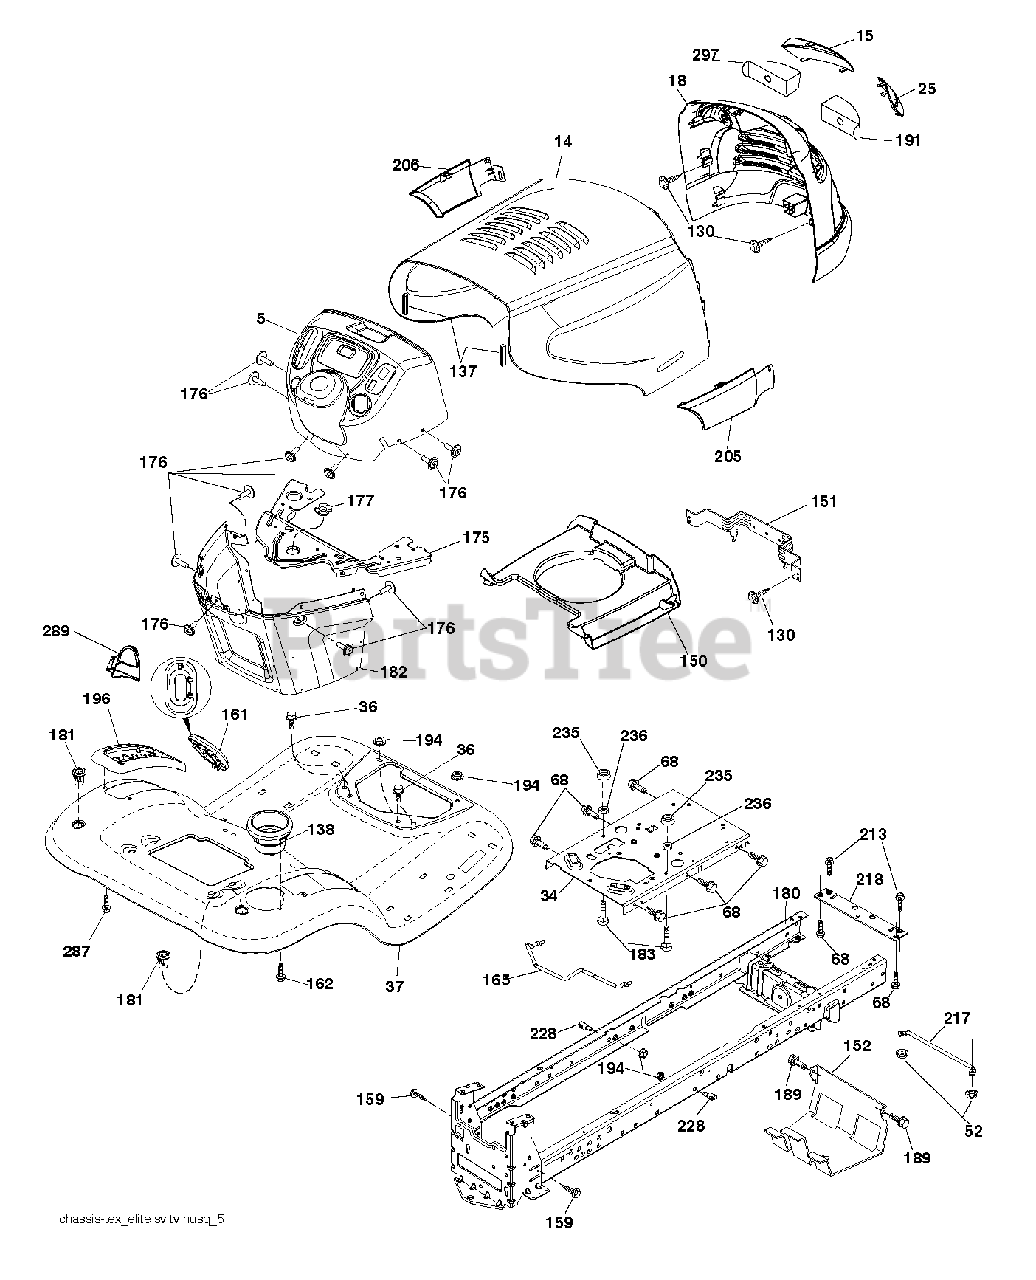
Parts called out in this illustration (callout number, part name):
5	DASH UPPER
14	HOOD.PNT.ELITE.TVENT.SVENT.SSK
18	GRILLE.ELITE HUSQ.BLACK.DL.
34	PLATE.ENGINE.WELDED.CHASSIS
36	SCREW 5/16"
52	LOCKNUT
68	SCREW LT
130	SCREW.#10 X 0.750.BOS (2 2)
137	BUMPER.HOOD.LARGE.1.75"
138	CUPHOLDER.TL.TEX.BLACK
150	AIR DUCT
151	BRACKET PIVOT
152	SHIELD.BROWNING.W/TEX
159	SCREW, 3/8-16X3/4
161	WINDOW.FUEL.LT.TEX.BLACK
162	SCREW.HI-LO.CONSOLE
165	SUPPORT.TANK.REAR.W/TEX
175	CROSSMEMBER.LT
176	SCREW.#10-24X5/8.RN.QU
177	BUSHING,STEERING
180	CHASSIS
181	FEND/FTRST.PCH.CPH.NFW
182	DASH.LOWER.LT.CCS
183	BOLT.5/16-18X1-1/4 FULL THD
189	SCREW
191	INSERT.REFLECTIVE.RH.
194	NUT LOCK HEX FLANGE 5/16-18
196	CONSOLE.ASM.DECKLFT.BL/RBT.TLT
205	SKIRT.SIDE.RH.ELITE.HUSQ.428
206	SKIRT.SIDE.LH.ELITE.HUSQ.BLACK
213	BOLT
217	ROD.PIVOT.HOOD
218	X-PIECE.HOOD.STOP.NON/
228	STUD.FASTNER.W/ANTI-ROTATE
235	SPACER FENDER
236	NUT.CENTERLOCK.5/16-
287	SCREW 1/4X20
289	PLUG CRUISE HOOK PHONE
297	INSERT LENS
